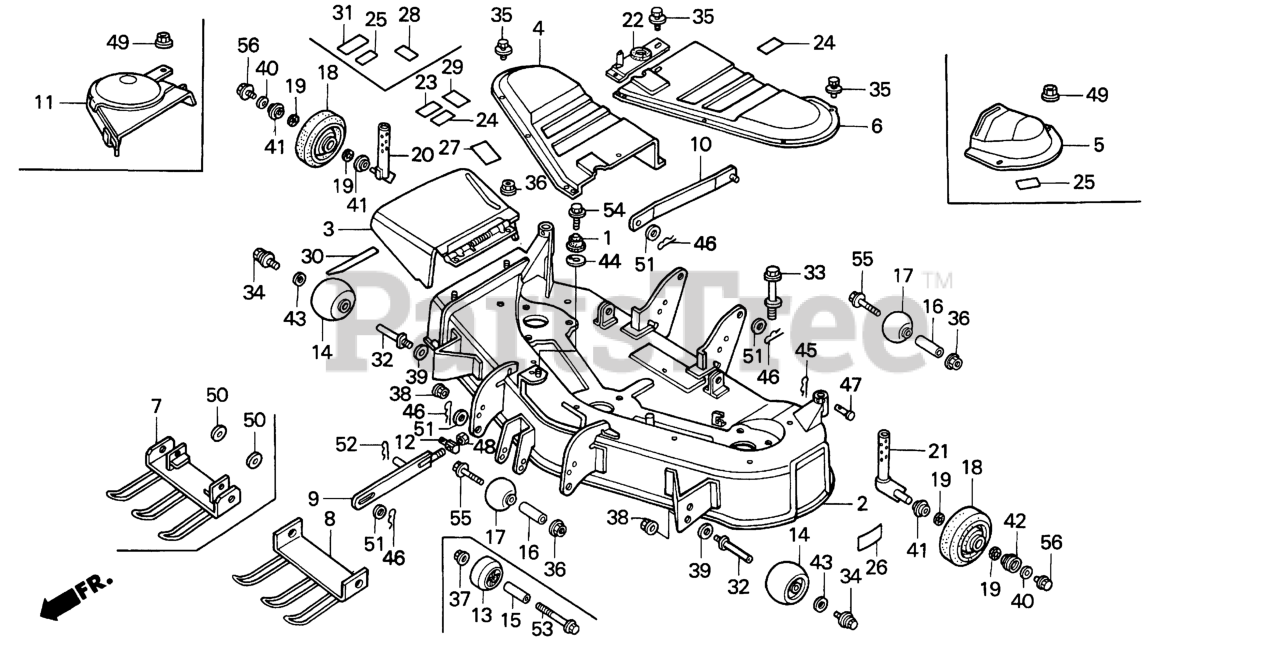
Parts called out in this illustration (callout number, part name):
1	RUBBER (LOWER) Use from Frame SN 1008046.
2	HOUSING, CUTTER
3	ADAPTER, DISCHARGE
5	COVER, L. BELT
7	PLATE, FR. LINK (LOWER)
9	LINK, FR. DECK
10	LINK, RR. DECK
11	STOPPER, BELT
12	PIN, FR. LINK ADJUSTING
13	ROLLER, ANTI-SCALP
14	ROLLER, ANTI-SCALP
15	COLLAR, ANTI-SCALP ROLLER
18	ROLLER ASSY., GAUGE
19	DUST SEAL, GAUGE ROLLER
20	ARM, R. GAUGE ROLLER
21	ARM, L. GAUGE ROLLER
25	LABEL A, WARNING (ENGLISH)
26	MARK, INCH SIZE (46)
28	MARK, HEIGHT ADJUSTING (ENGLISH)
31	MARK, DANGER
32	SHAFT, ANTI-SCALP ROLLER
33	BOLT, BELT STOPPER
34	BOLT, WHEEL
36	NUT, FLANGE (8MM)
37	NUT, U (10MM) (FUSE RASHI)
38	NUT, SELF-LOCK (12MM)
39	WASHER, THRUST (12MM)
40	WASHER (10.5X27)
40	WASHER (10.5X27X4)
41	COLLAR, GAUGE ROLLER
42	COLLAR, GAUGE ROLLER
43	WASHER (8MM)
44	WASHER (40MM)
45	PIN, SNAP (7MM)
46	PIN, LOCK (14MM)
47	PIN B, WHEEL
48	NUT, HEX. (12MM)
49	NUT, FLANGE (8MM)
50	WASHER, PLAIN (12MM)
51	WASHER, PLAIN (14MM)
52	PIN, LOCK (12MM)
53	BOLT, FLANGE (10X110)
54	BOLT, FLANGE (6X14)
56	BOLT, FLANGE (10X16) (NA USE ALT:95700-10016-08)
